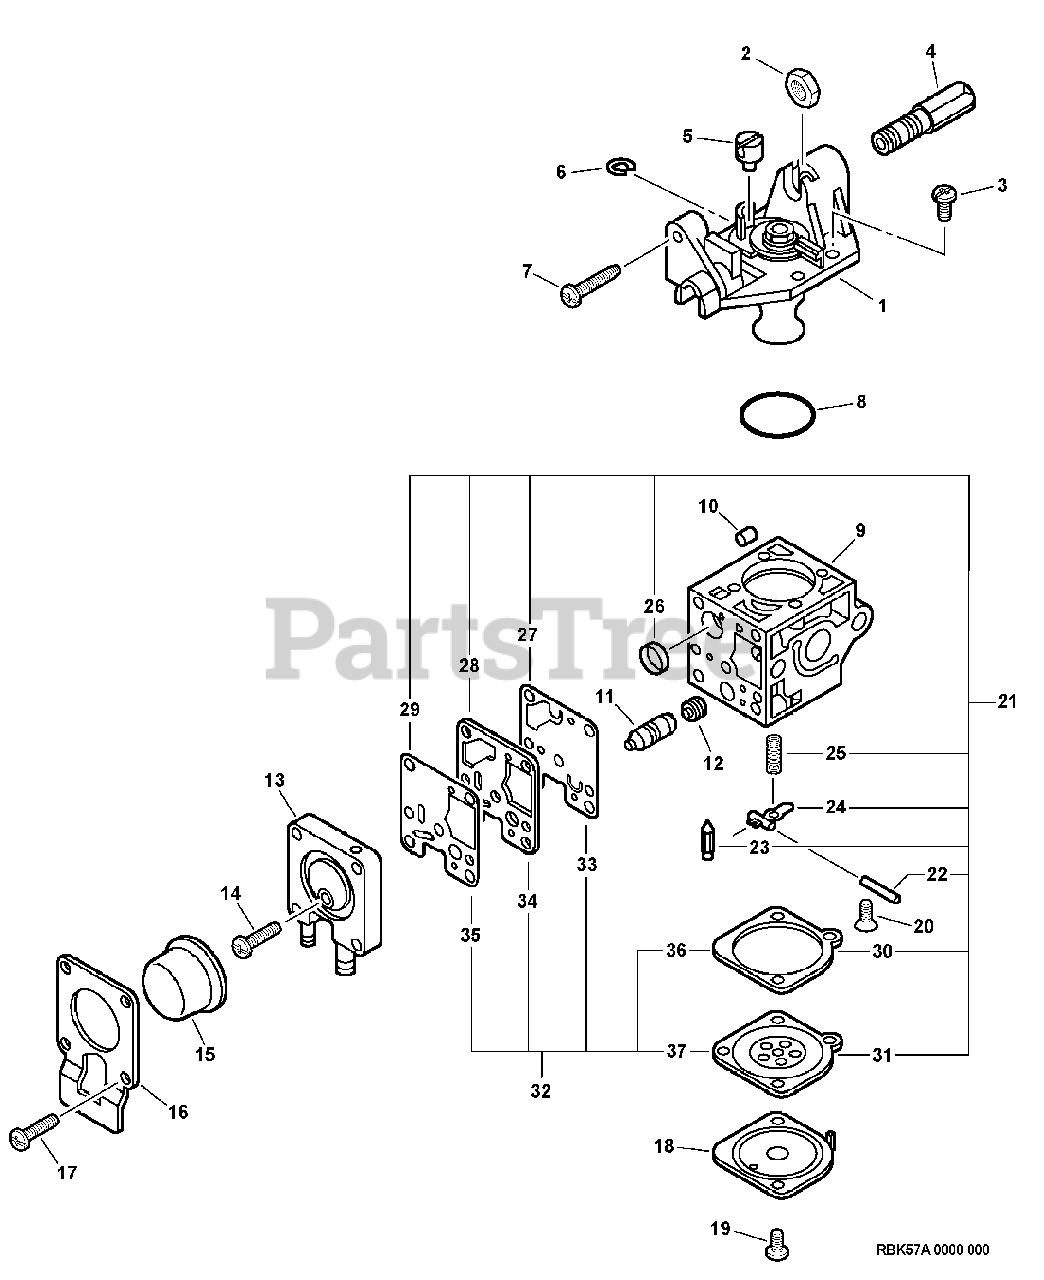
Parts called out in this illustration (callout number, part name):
1	ROTOR COVER ASSY
4	NUT, CABLE ADJUST
6	RING, RETAINING
7	SCREW, IDLE ADJUST
9	BODY, CARBURETOR
10	GUIDE, ROLLER
11	PLUG KIT
13	BASE, PURGE
14	SCREW, PURGE BASE
15	BULB, PURGE
16	RETAINER, PURGE BULB
17	SCREW, RETAINER
18	COVER, METERING
20	SCREW, METERING LEVER PIN
21	REPAIR KIT
22	PIN, METERING LEVER
23	VALVE, INLET NEEDLE
24	LEVER, METERING
25	SPRING, METERING LEVER
26	STRAINER
27	DIAPHRAGM, PUMP
28	GASKET, PUMP
29	DIAPHRAGM, SURGE
30	GASKET, DIAPHRAGM
31	DIAPHRAGM, METERING
32	DIAPHRAGM/GASKET KIT
33	DIAPHRAGM, PUMP
34	GASKET, PUMP
35	DIAPHRAGM, SURGE
36	GASKET, DIAPHRAGM
37	DIAPHRAGM, METERING
